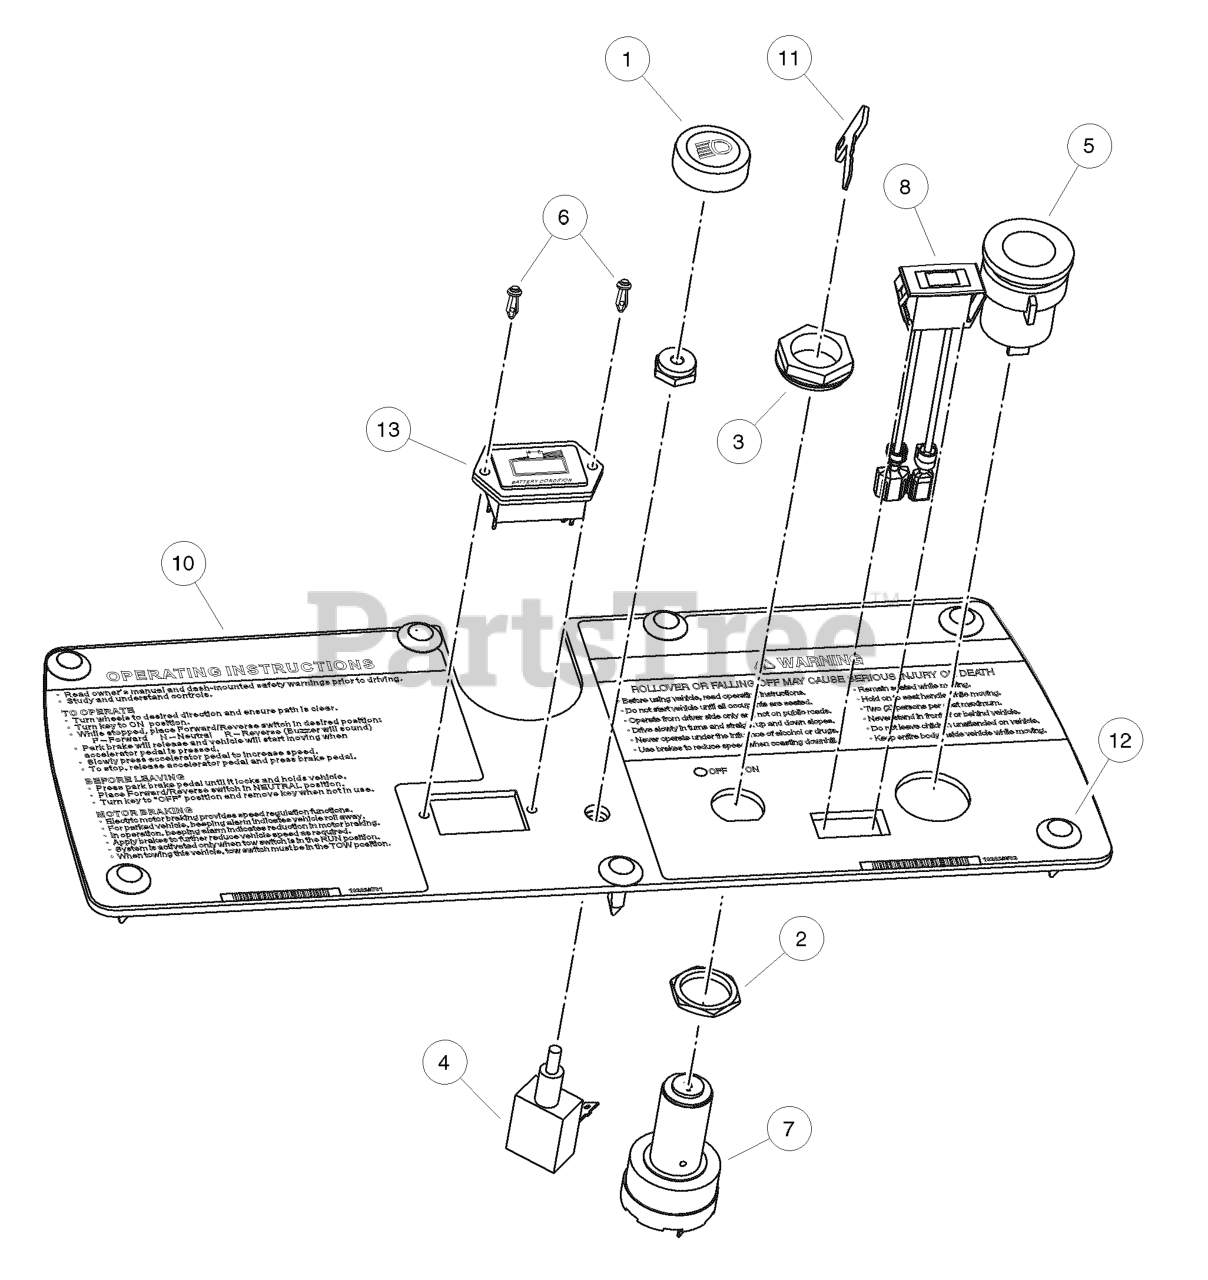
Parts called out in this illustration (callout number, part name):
1	LIGHT SWITCH KNOB
2	NUT, KEYSWITCH
3	NUT, KEYSWITCH
4	SWITCH, LIGHT
5	ACCESSORY RECEPTACLE
6	Rivet, Micro Tuflok
7	KEY SWITCH ELECT PREC
8	BATTERY LIGHT PREC
9	PANEL, INSTRUMENT, E
10	PANEL, INSTRMT, E W/12
11	KEY SET, OEM
12	SCREW, TUFLOK PANEL, 1/4
13	INDICATOR, BATT CHRG, 48V
